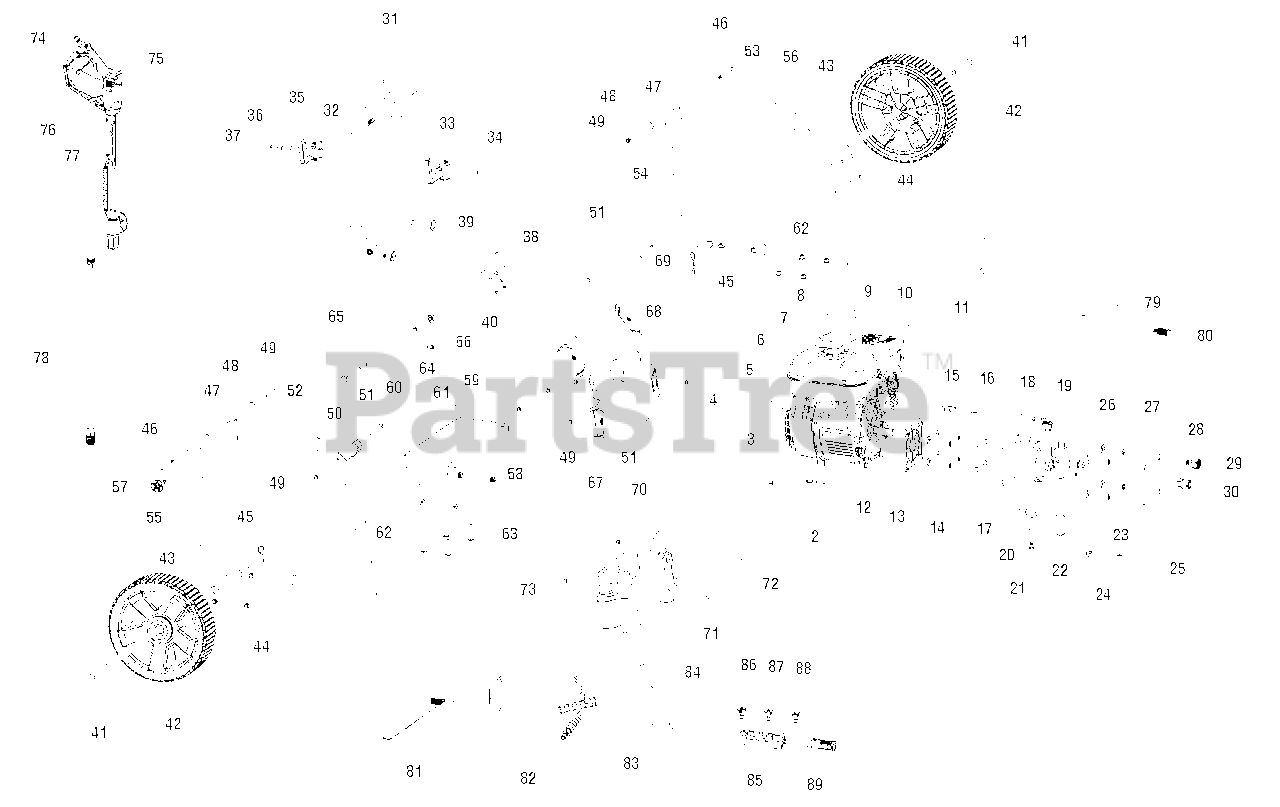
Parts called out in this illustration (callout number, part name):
1	Engine (Subaru, SP 170, Hori, EPA)
2	Oil Dipstick Label
3	Lubricant Label
4	UL Fire Warning Label Spark Arrestor)
5	License Label
6	Warning Label
7	Pressure Release Label
8	Do Not Mix Label
9	Hot Muffler Label
10	E85 Label
11	Warning Hangtag
12	Washer (5/16 in.)
13	Lock Washer (5/16 in.)
14	Bolt (5/16-24 x 3/4 in., Hex Hd.)
15	Thermal Release Valve
16	Output Shaft Key (27 mm)
17	Pump Assembly (3GXT27)
18	Vent Tube (11 in.)
20	Idle Down Assembly
21	Bolt (M10 x 1.5 in., Special)
22	Compression Seal
23	Unloader Cap
24	Cable Clamp (Engine)
25	Swivel Bushing
26	Washer (3/8 in.)
27	Lock Washer (3/8 in.)
28	Bolt (3/8-16 x 1-3/8 in., Hex Hd.)
29	Garden Hose Coupler w/Filter
30	3/8 in. Quick Connect (NPT)
31	Handle Assembly
32	Rear Hook
33	Front Hook
34	Screw (1/4-20 x .75 in.)
35	Washer (1/4 in.)
36	Lock Nut (1/4-20)
37	Screw (8-10 x 3/4 in., Truss Hd.)
38	Wand Storage (Front)
39	Bolt (M5 x 16 mm, Pan Hd.)
40	Hex Nut (M5)
43	Washer (1/4 in.)
44	Bolt w/Washer (M8 x 55 mm, Hex Hd.)
45	Cotter Pin
46	Connector Pin (1/4 in.)
47	Washer (OD20 x ID8 x 4.5t)
48	Washer (1/4 in.)
49	Lock Nut (1/4-20)
50	Lower Wand Holder
51	Screw (1/4-20 x 1.85 in., T30 Torx Hd.)
52	Release Pin Label
53	Hot Surface Label
54	Quick Start Label (Engine)
55	Frame Assembly (Right)
56	Frame Assembly (Left)
57	Handle Lock Assembly
58	Engine Plate
59	Data Label
60	Quick Start Label (Pump)
61	Add Oil Label
62	Flange Lock Nut (M8)
63	Bolt (M8 x 45 mm, Flange Hd.)
65	Acorn Nut
66	Cable Clamp (Frame)
67	Face Plate
68	Performance Label
69	Idle Control Label
71	Logo Label
72	Screw (1/2-20 x 1.75 in.)
73	Lock Nut (1/4-20)
74	Trigger Handle Assembly
75	Warning Label
76	Trigger Guard Warning Label
77	Max Rating Label
78	Wand
79	Chemical Siphon Tube
80	Chemical Siphon Filter
81	Velcro Strap
82	Hose Assembly (30 ft.)
83	Carabineer
85	Nozzle Holder
86	40deg Nozzle
87	25deg Nozzle
88	0deg Nozzle
89	Soap Nozzle
